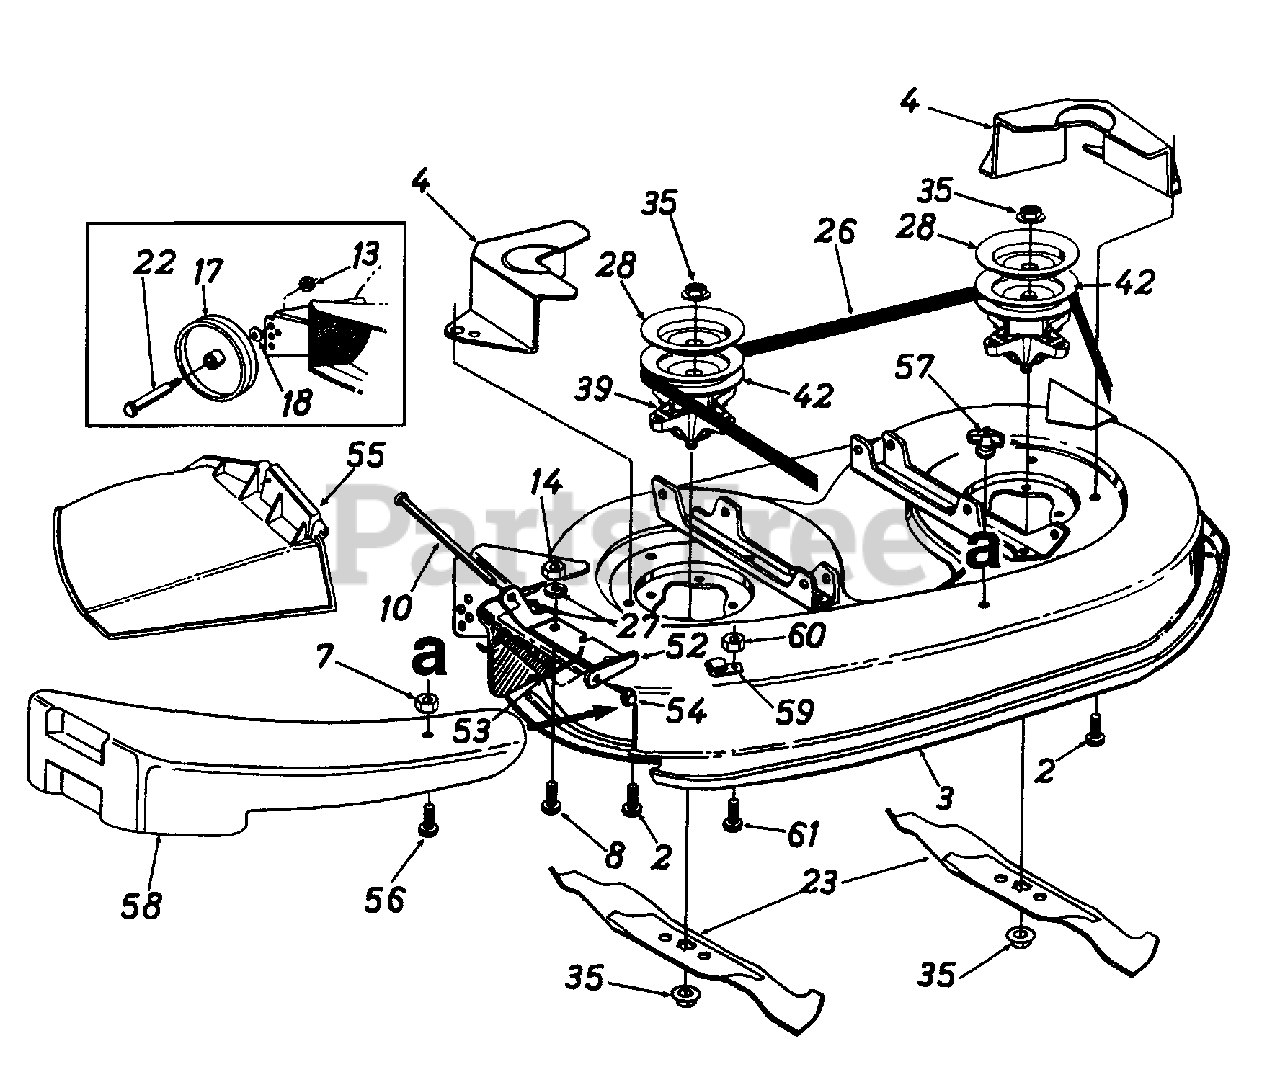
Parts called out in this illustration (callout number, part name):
2	Hex Wash. Hd. TT-Tap Scr. 5/16-18 x .75" Lg.
7	Hex L-Nut 1/4-20 Thd.
8	Hex Bolt 1/4-20 x .62"
10	Hinge Pin
13	Hex Top L-Nut 3/8-16 Thd.
14	Hex Nut 1/4-20 Thd. (Gr. 5)
17	Deck Wheel - 5"
18	Bell-Wash. .40" I.D. x .88" O.D.
22	Shld. Bolt .498" Dia. x 1.53"
23	3 in 1 Blade
26	V-Belt
27	Bell-Wash. 1/4" I.D.
28	Brake Disc
35	Hex Flange Nut 5/8-18 Thd.
39	Blade Spindle Ass'y. Comp.
42	5" Dia. Pulley
52	Hinge Mtg. Brkt.
53	Torsion Spring
54	Push Nut
55	Chute Ass'y Comp.
56	Hex Bolt 1/4-20 x 1" Lg.
57	Wing Nut 1/4-20 Thd.
58	Mulching Plug
59	Retainer Hook Brkt
60	Hex Sems Nut 1/4-20 Thd.
61	Hex Bolt 1/4-20 x .62" Lg
